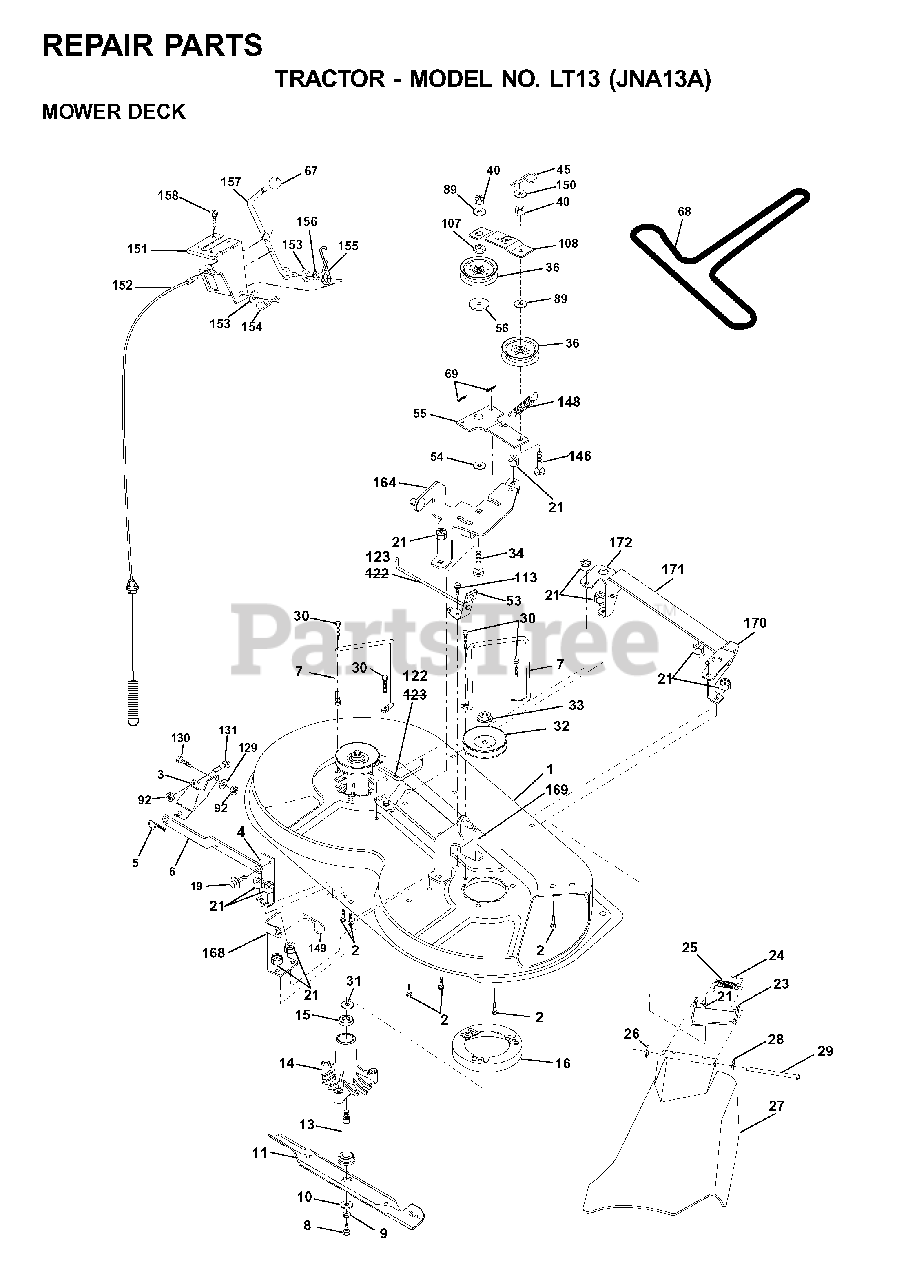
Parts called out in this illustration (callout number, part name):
2	BOLT
3	BRKT ASM SWAY BAR
5	RETAINER-SPRNG RB
6	REAR SUSP ARM
7	KEEPER LH
8	BLADE BOLT
9	LOCKWASHER
10	WASHER.BLADE
11	BLADE, HI-LIFT 36" PREMIUM
13	SHAFT ASM VENT
14	HSG MANDREL
16	STRIPPER, MWR ROUND
19	BOLT SHD 5/16-18
21	LOCKNUT
23	BRACKET ASM DEFLECTOR
24	CAP-SLEEVE LT
25	SPRING TORSION
26	NUT PUSH M
28	WASHER
29	HINGE ROD
30	SCREW THDROL ROLLING WASHER HD
31	WASHER
32	PULLEY, MANDREL
33	NUT
34	BOLT
36	FLAT IDLER PULLEY
40	LOCKNUT
45	RETAINER M
53	BRAKE ASSEMBLY
54	HARDENED WASHER
55	IDLER ARM
56	SPACER.RETAINER.MOWER
67	KNOB T (3/8 HOLE)
69	COTTER PIN
89	WASHER GT
92	NUT
107	SPACER.IDLER.ARM
108	STIFFENER.IDLER.ARM
129	WASHER
131	BOLT D
146	BOLT, CARRIAGE IDLER
148	IDLER RETURN SPRING
149	SPRING.RETAINER.YELLOW.ZINC
150	WASHER PM
151	BRACKET, CLUTCH CABLE
153	WASHER FLAT 3/8"
154	SPRING RETAINER
155	SPRING RETENTION LEVER
156	SPACER CLUTCH CABLE
157	ROD CLUTCH CABLE 3/8"
158	SCREW LT
171	BRACE
